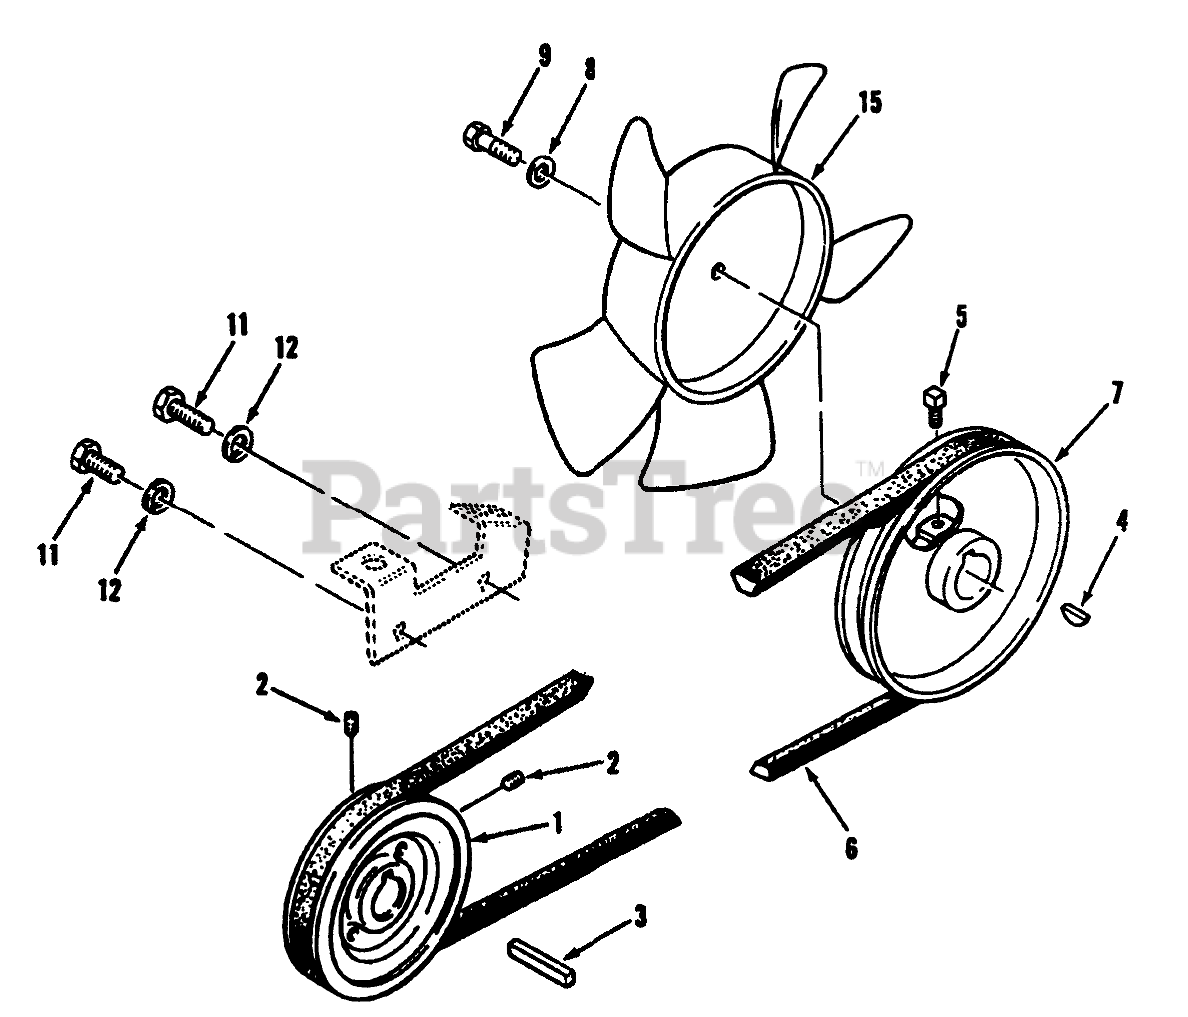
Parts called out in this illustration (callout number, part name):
1	PULLEY
2	SCREW-SET, HSH
4	KEY-WOODRUFF
5	SCREW-SQH
6	BELT-V
7	PULLEY
8	WASHER
9	SCREW-HH
11	SCREW-HH, LOCK
12	WASHER-PLAIN
15	NYLON FAN-L-CW
